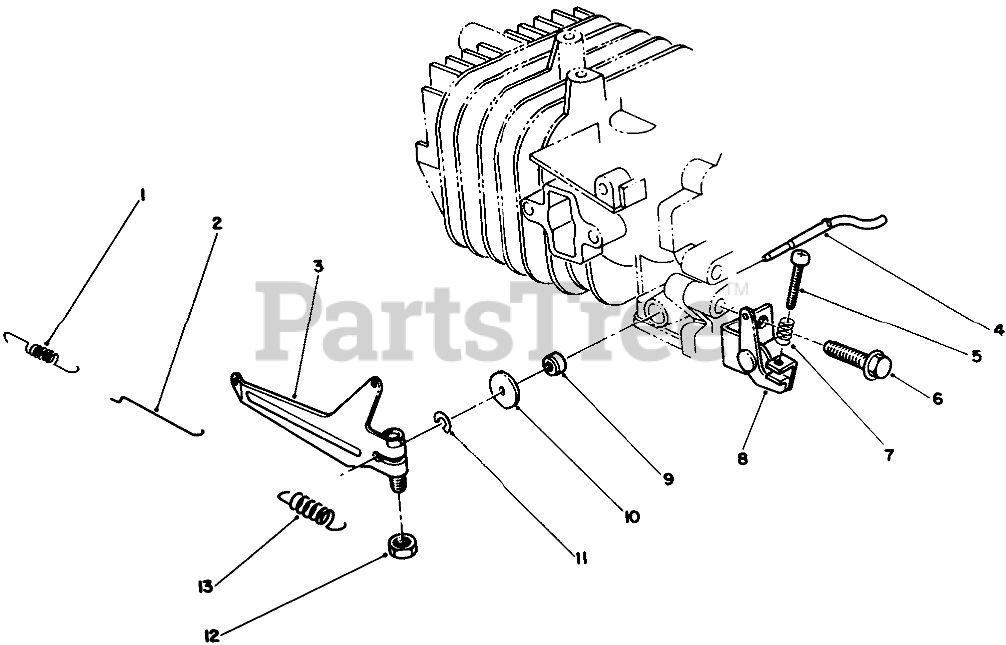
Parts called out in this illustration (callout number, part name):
1	CARB SPRING
2	CARB ROD
3	GOVERNOR ARM
4	SHAFT
5	SCREW
7	SPRING
8	GOV SPR BRKT
9	SEAL-OIL
10	WASHER
11	E-RING
13	GOV SPRING
